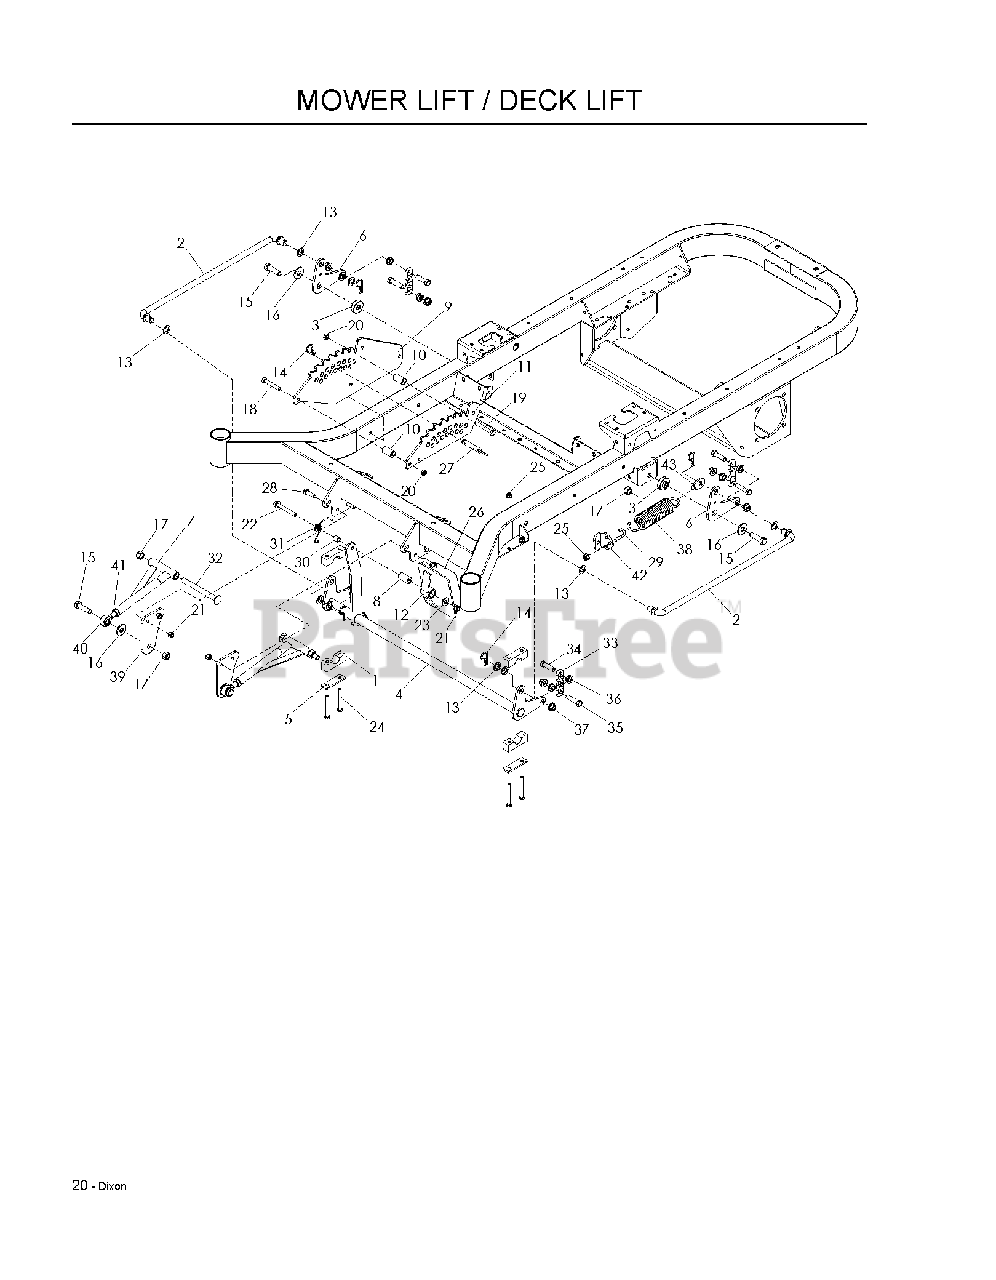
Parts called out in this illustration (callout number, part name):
1	PILLOW BLOCK
2	CROSS LINK
3	IDLER SPACER
4	SHAFT, LIFT, DECK
5	REINFORCEMENT BAR
6	BELLCRANK, REAR LIFT
7	STRUT, DECK, BLK
8	BUSHING, SLEEVE
9	PLATE, 5" HEIGHT
10	DECK LIFT SPACER
11	PLATE, INSIDE 5", HEIGHT
12	PEDAL, FOOT, WELDMENT
13	BUSHING
14	PIN, COTTER 1 3/4
15	HCS 1/2-13 X 1 3/4 GR 8
16	WASH USS FLAT 1/2
17	NUT 1/2-13 HEX NYLOC ZD
18	HCS 3/8C X 2 1/4
19	HCS 3/8C X 2 1/2
20	NUT HEX 3/8-16 NYLON, THIN
21	NUT 3/8-16 NYLOC
22	HHFS 3/8-16 X 2 3/4
23	WASHER 3/8 FLAT
24	HCS 5/16C X 2-3/4
25	5/16-18 NYLOC FLANGE NUT
26	FOOT PAD
27	HITCH PIN
28	HCS 3/8C X 1 1/4 GR5
31	SPRING, TORSION
32	1/2-13X5-1/2 CAR BLT
33	LIFT CHAIN - 3 LINK
34	HCS 7/16C X 1 1/2
35	HCS 7/16 - 14 X 1 3/4
36	NUT 7/16C WHIZ
37	NUT 7/16-14 HEX WHIZ LK
39	MOUNT, STRUT
40	ROD END
41	NUT 1/2-20 HEX JAM ZD
42	MOUNT, SPRING
43	TAB, SPRING
